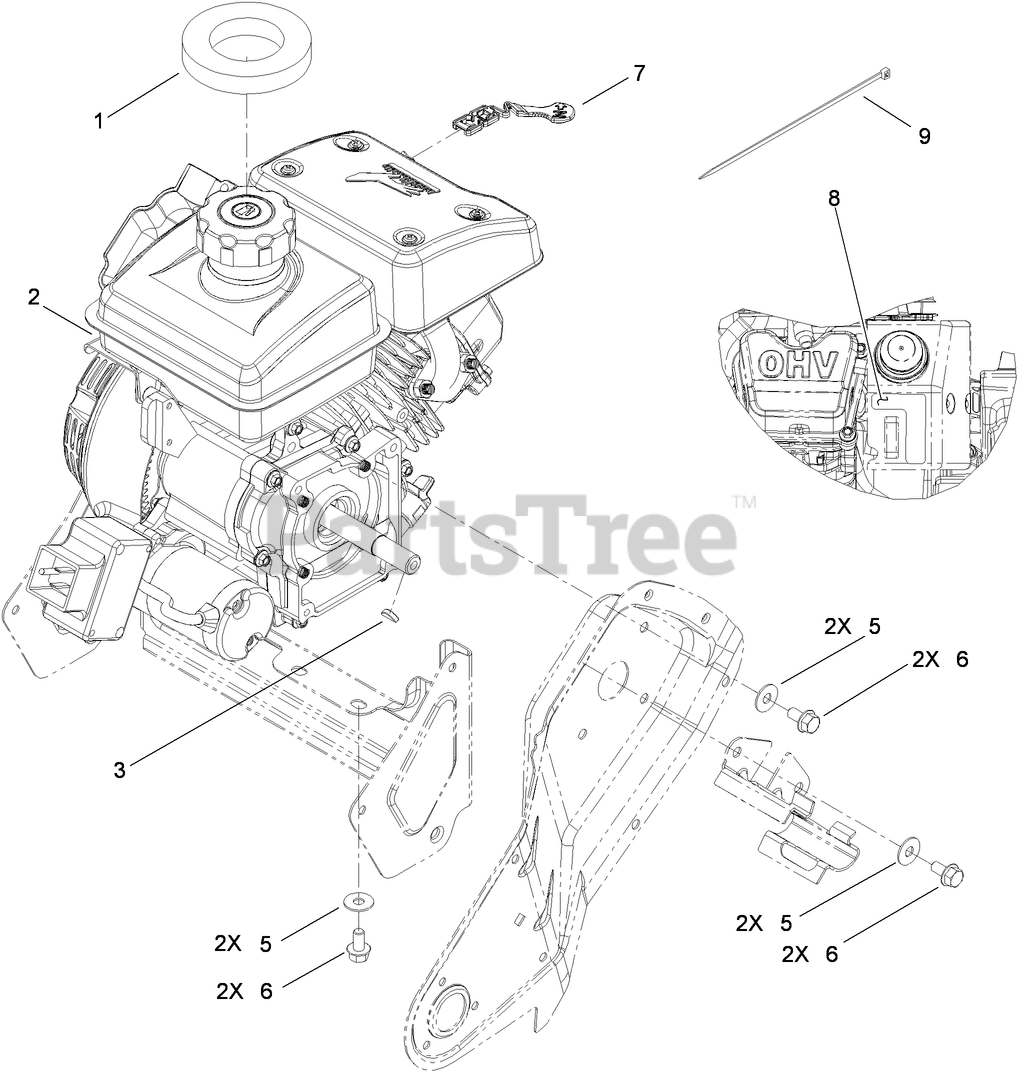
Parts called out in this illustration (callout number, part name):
1	SEAL-TANK
2	ENGINE-154
3	KEY-WOODRUFF
5	WASHER-BELLEVILLE
6	SCREW-HHF
7	LEVER-CHOKE
8	DECAL-CONTROL, ENGINE
9	TIE-CABLE
